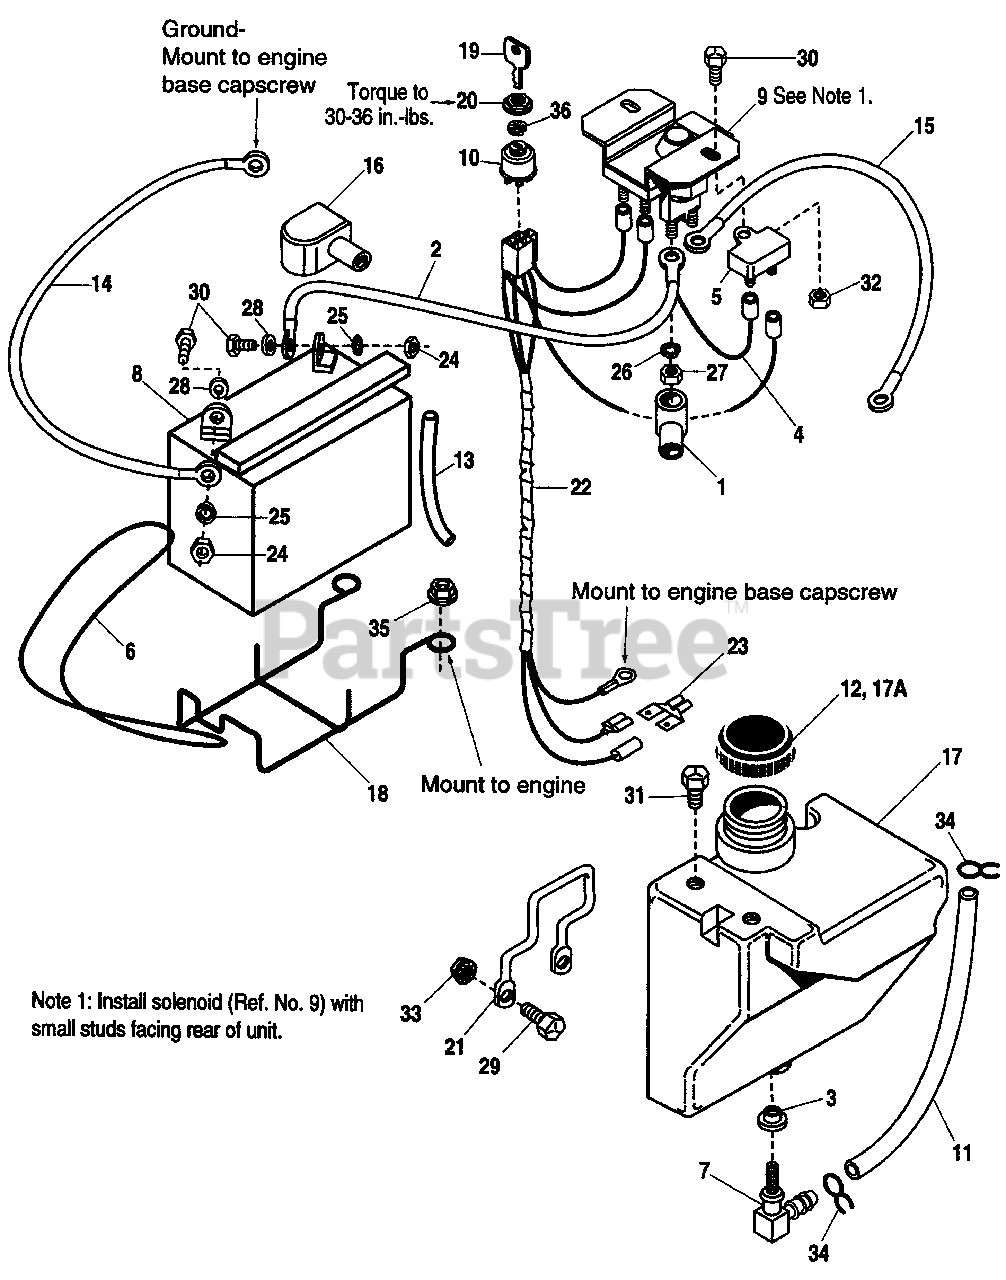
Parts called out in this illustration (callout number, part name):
1	COVER, Terminal
2	WIRE, Battery to Solenoid, 8"
3	BUSHING, Fuel Tank
4	WIRE, Circuit Breaker to Tab Adapter
5	CIRCUIT BREAKER
6	STRAP, Battery
7	ELBOW, Fuel Tank
8	BATTERY
9	SOLENOID
10	IGNITION SWITCH (Incl. Ref. Nos. 19, 20 & 36)
11	HOSE, Fuel Tank
12	CAP, Fuel Tank, w/built in fuel gauge (Used on black tank)
13	HOSE, Drain, 9"
14	WIRE, Battery to Gound, 15"
15	WIRE, Solenoid to Starter, 15"
16	BOOT, Battery
17A	CAP, Fuel Tank, vented (Used on clear tank)
18	SUPPORT, Battery
19	KEY, Ignition Switch
20	NUT, Ignition Switch
21	SUPPORT, Fuel Tank
22	WIRING HARNESS
23	TAB, Adapter
24	NUT, Hex, 1/4-20
25	LOCKWASHER, 1/4
26	LOCKWASHER, 5/16
27	NUT, Hex, 5/16-24
28	WASHER, 1/4
29	CAPSCREW, Hex Hd., 5/16-18 x 3/4
30	CAPSCREW, Hex Hd. 1/4-20 x 3/4
31	SCREW, Hex Whizlock, 5/16-18 x 1/2
32	NUT, 2-way Lock, 1/4-20
33	NUT, Serrated, Flange Lock, 5/16-18
34	CLAMP, Hose
35	NUT, Hex, Large Flange, "C" Lock, 3/8-16
36	LOCKWASHER, Internal Tooth, 5/8
